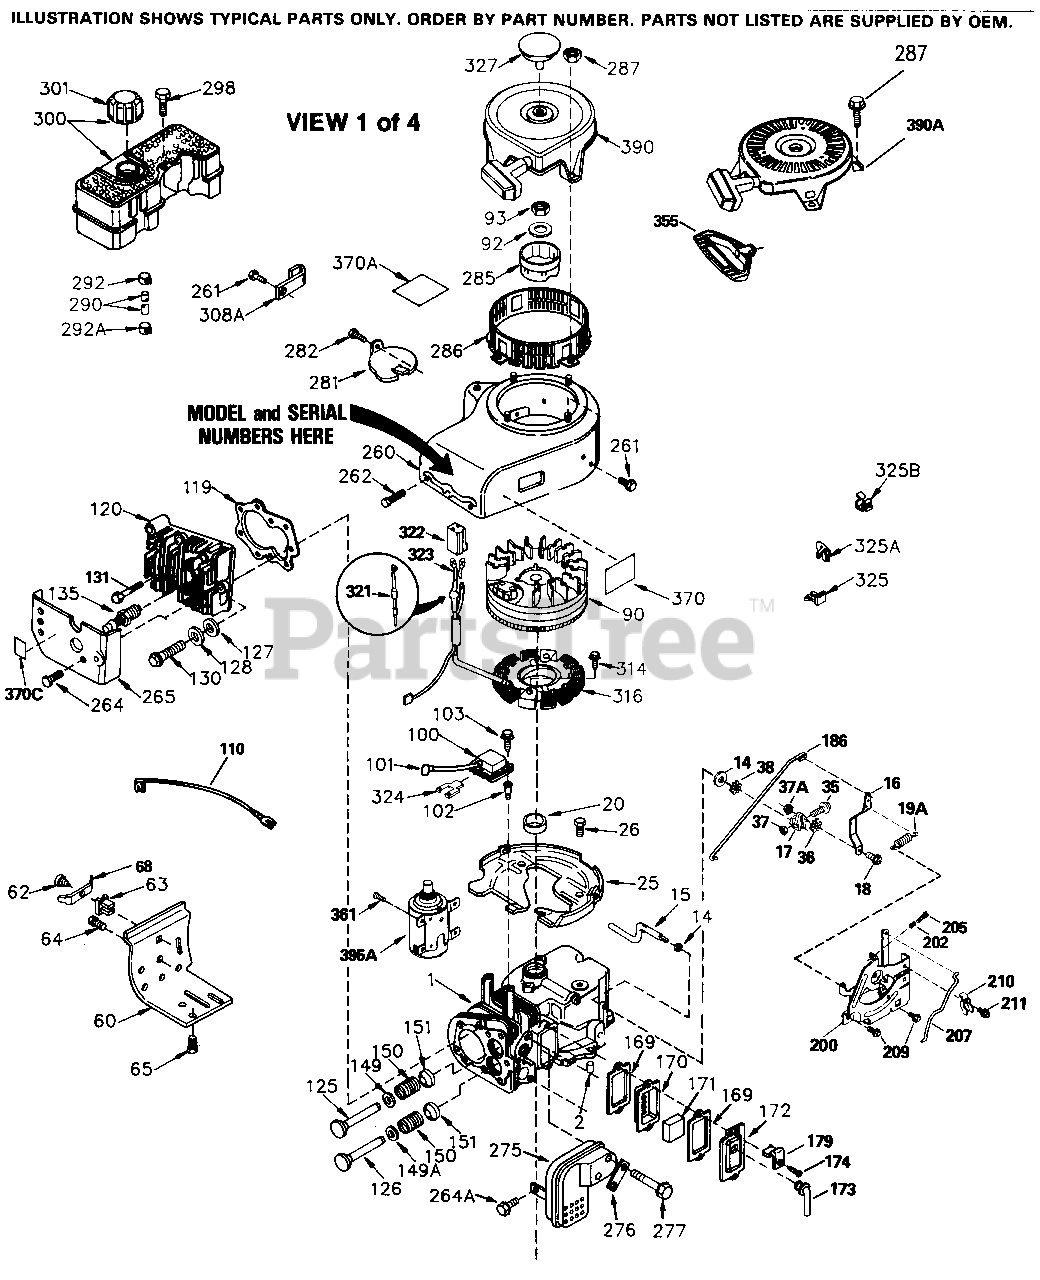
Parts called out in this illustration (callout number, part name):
1	"Cylinder (Incl. 2 & 20) )
2	Dowel Pin
14	Flat Washer
15	Governor Rod
16	Governor Lever
17	Governor Lever Clamp
18	Screw, 8-32 x 5/16"
19A	Extension Spring
20	Oil Seal
26	Screw, 1/4-20 x 5/8"
51	Counterbalance Weight
60	Blower Housing Extension
62	Screw, 8-32 x 3/8"
63	Breather Tube Grommet
64	Screw, T-30, 1/4-20 x 1/2"
65	Screw, 10-24 x 1/2"
68	Ground Terminal
90	Flywheel (3 amp w/ring gear)
92	Lock Washer
93	Flywheel Nut, 5/8-18
100	Solid State Ignition
101	Spark Plug Cover (use as required)
102	Solid State Mounting Stud
103	Screw, Torx T-15, 10-24 x 1"
119	* Cylinder Head Gasket
120	Cylinder Head
125	Exhaust Valve (Std.)(Incl. 151)
126	Intake Valve (Std.) (Incl. 151)
127	Washer (Do not use with 6021A screw)
128	Belleville Washer
130	Screw, 5/16-18 x 2"
131	Screw, 5/16-18 x 1-1/2" Do not use w /650691
135	Resistor Spark Plug - RJ17LM
149	Valve Spring Cap
150	Valve Spring
151	Valve Spring Keeper
169	* Valve Cover Gasket
170	Breather Body
171	Breather Element
172	Valve Cover
173	Breather Tube
174	Screw, 10-24 x 1/2"
186	Governor Link
200	Control Bracket
202	Compression Spring
205	Screw, 6-32 x 21/32"
209	Screw, 10-24 x 9/16"
210	Conduit Clip
211	Screw, 10-32 x 3/8"
238	Screw, 10-32 x 1-17/32"
245A	Pre-Cleaner Air Filter also available in Packaged Part #740015B
260	Blower Housing (for electric starter) NOTE: Replacement hardware may diffe r when servicing starter assy. or blo wer housing. Refer to Service Bulleti n 508.
261	Screw, 5/16-18 x 3/4"
262	Screw, T-40, 5/16-24 x 21/32"
264	Screw, 1/4-20 x 5/8"
265	Cylinder Head Cover
275	Muffler
276	Locking Plate
277	Screw, 5/16-18 x 3-3/16"
281	Starter Bubble Cover
282	Screw, 8-32 x 3/8"
286	Debris Screen
287	Screw, 10-32 x 13/32"
290	Fuel Line (braided 16") (40cm)
292	Fuel Line Clamp
298	Screw, 10-32 x 35/64"
300	Fuel Tank (Incl. 292, 298 & 301)
301	Fuel Cap (Red) NOTE: This tank was b uilt with different size fuel inlet o penings. Tanks with the l-l/2" I.D. o pening use fuel cap 33032. Tanks wit h the 1-3/4" I.D. opening use fuel ca p 35355.
314	Screw, 1/4-20 x 3/4"
315	Alt. Coil (3 Amp DC) Incl. 321, 322 & 323
322	Connector Body
323	Terminal
324	Terminal
325	Wire Clip
325A	Wire Clip
325B	Wire Clip
327	Starter Plug
370	Instruction Decal
370A	Name Decal
370C	Decal - Important Lubrication - SAE 3
390A	Rewind Starter & Cup Ass`Y. This asse mbly replaces 590633 starter
